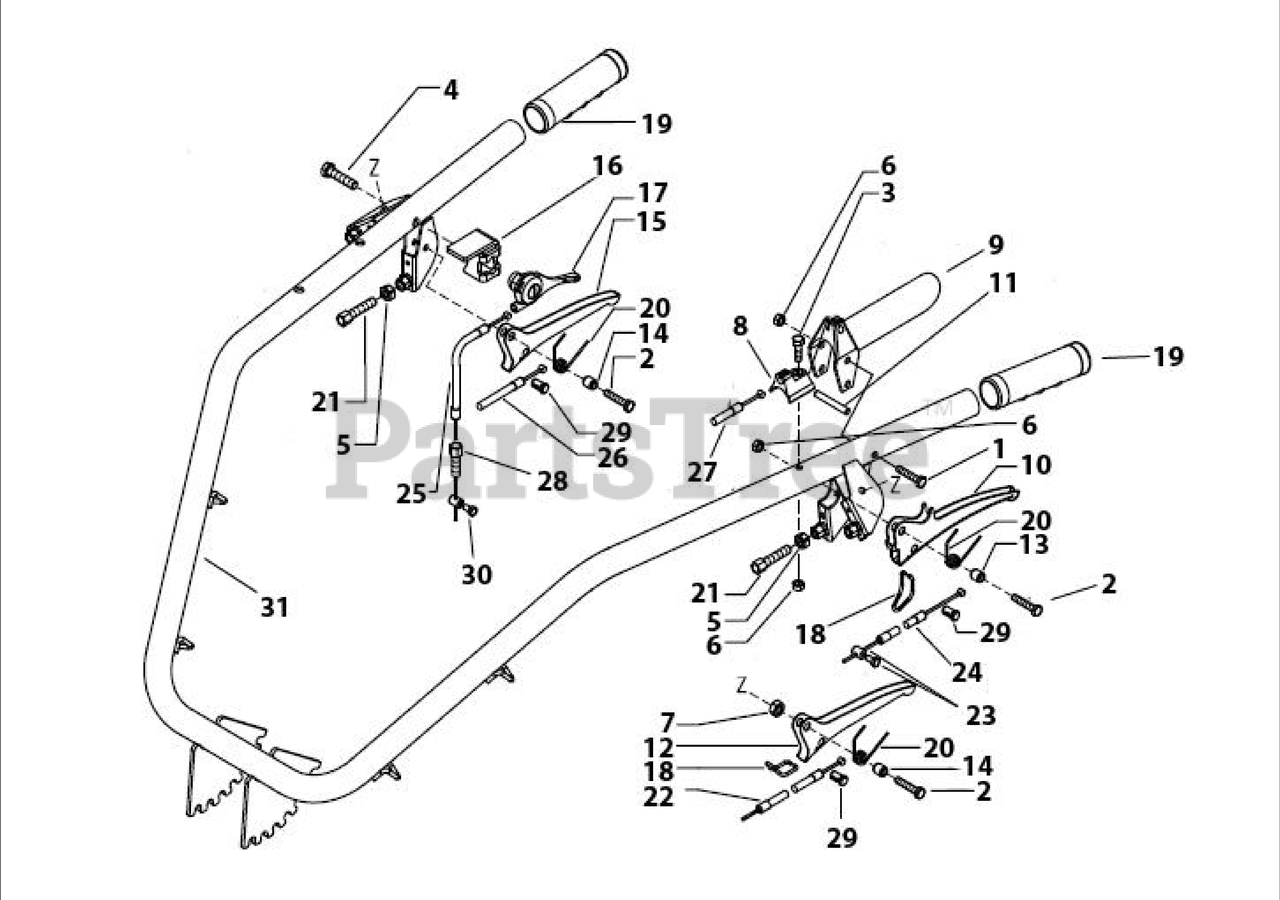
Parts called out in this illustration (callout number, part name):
1	CAP SCREW, M6X45
2	CAP SCREW, M6X25
3	CAP SCREW, M6X35
4	SCREW
5	NUT, M8
6	NUT, SELF LOCK M6
7	NUT, SELF LOCKING M8
8	CABLE GUIDE
9	LEVER, MOTOR STOP ( OPC)
10	LEVER, CLUTCH
11	PIN, MOTOR STOP LEVER
12	LEVER, BRAKE (LEFT OR RIGHT)
13	SPACER, LEVER
14	SPACER, LEVER
15	LEVER, STEERING RELEASE
16	PANEL
17	LEVER, THROTTLE
18	CLIP, WIRE STOP
19	GRIP (LEFT OR RIGHT)
20	SPRING, LEVER
21	SCREW, ADJUSTING M8
22	CABLE & SHEATH BRAKE (L OR R)
23	CLAMP, CABLE
24	CLUTCH CABLE
25	CABLE, THROTTLE
26	CABLE, STEERING RELEASE
27	CABLE, LEVER MOTOR STOP (OPC)
28	SCREW, ADJUSTING M6
29	BARREL
30	CLAMP, THROTTLE
31	HANDLEBAR
